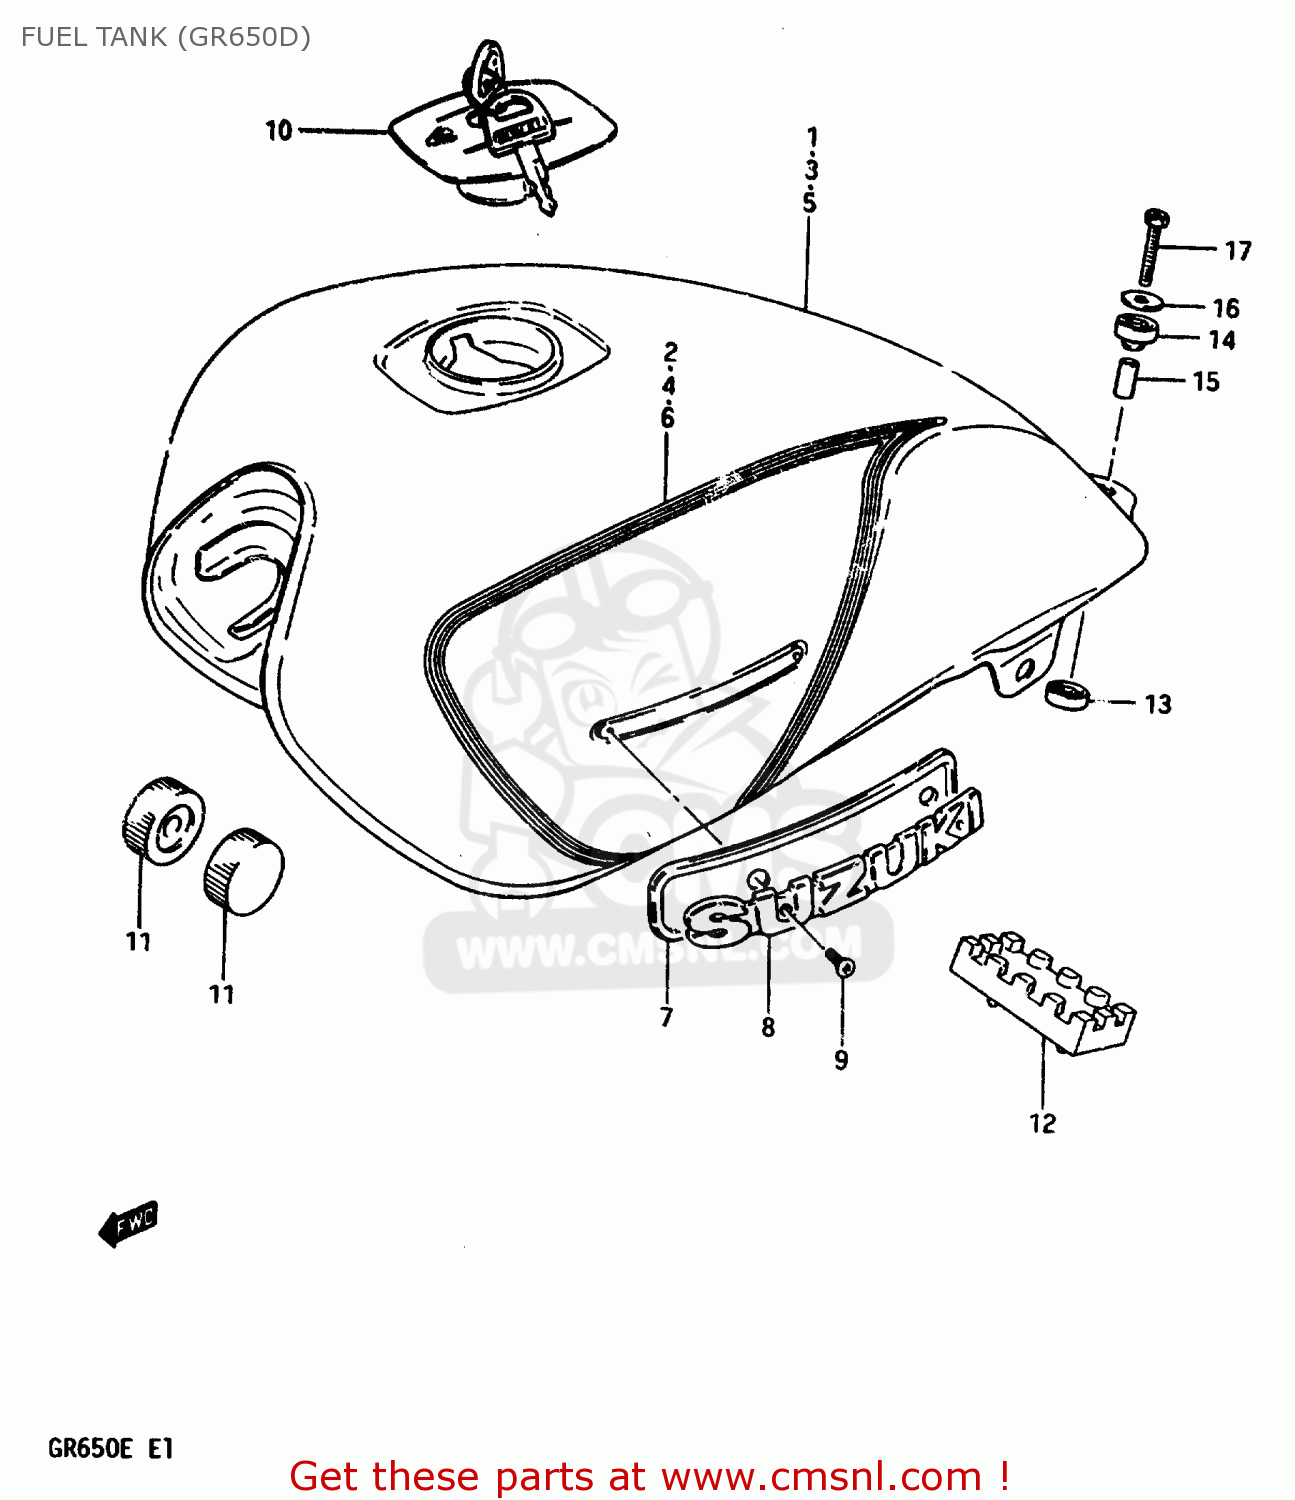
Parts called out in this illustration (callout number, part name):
1	TANK ASSEMBLY,FUEL
2	TAPE SET,FUEL TANK
3	TANK, FUEL
4	TAPE SET
5	TANK ASSY, FUEL
6	TAPE SET, FUEL TANK
7	CUSHION
8	EMBLEM,FUEL TANK
9	SCREW 3X6
10	CAP SET,FUEL TANK
11	CUSHION
12	CUSHION,FUEL TANK CTR
13	CUSHION
14	CUSHION
15	SPACER
16	WASHER (6.5X24X1.6)
17	BOLT
